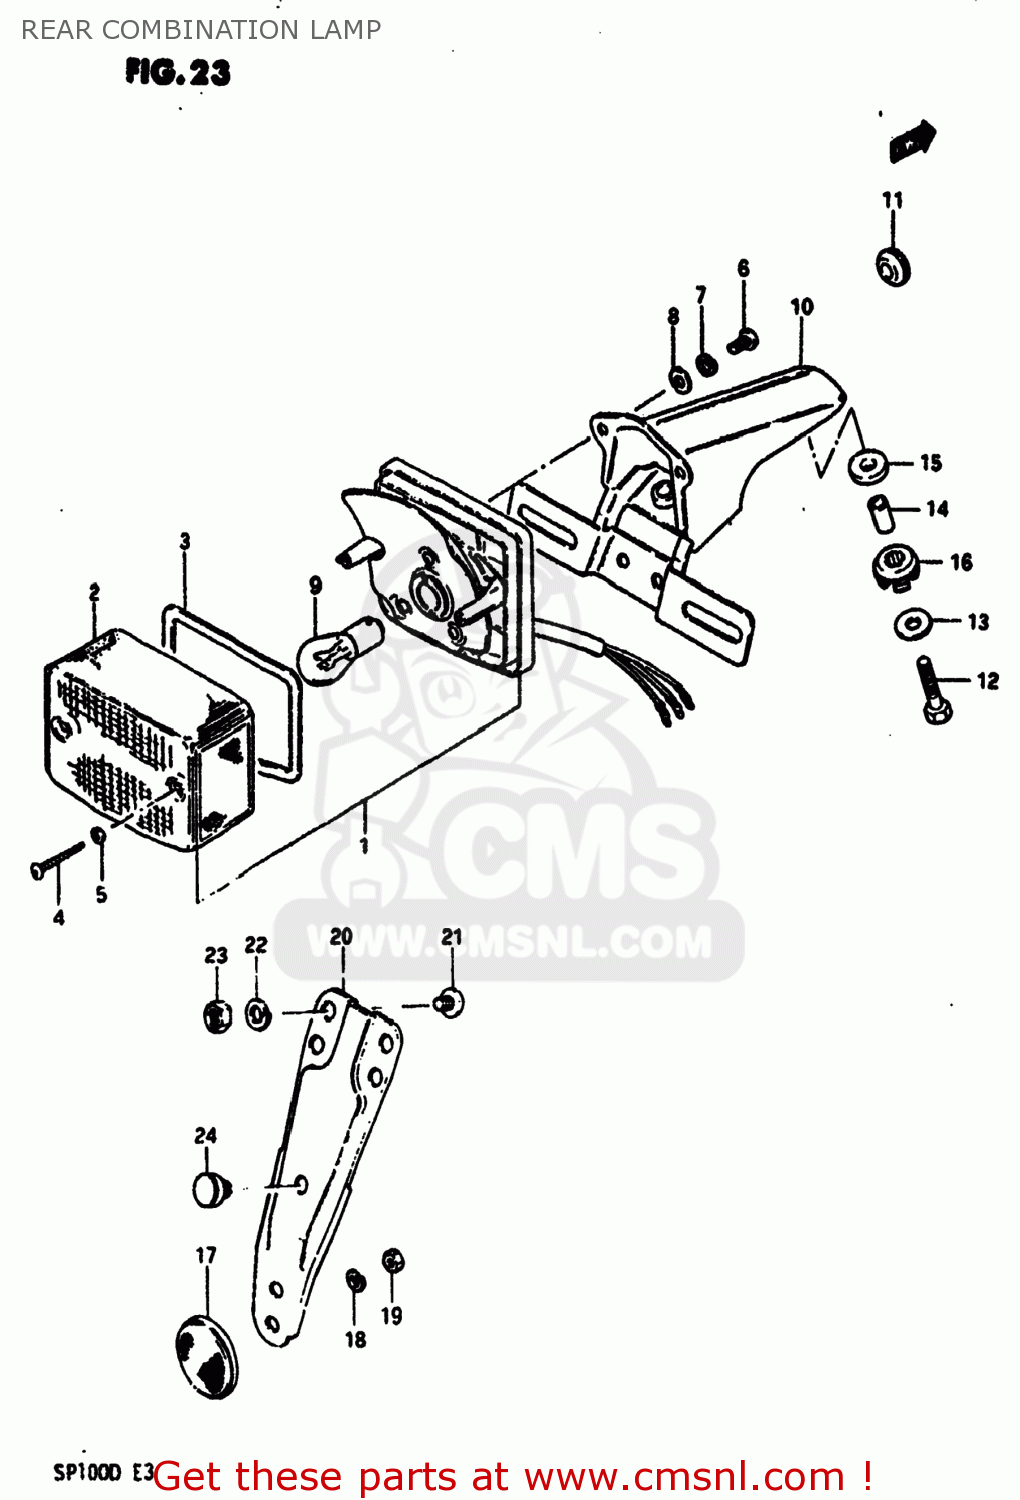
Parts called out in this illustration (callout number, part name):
1	LAMP UNIT,REAR COMBINATION
2	LENS
3	GASKET (NAS)
4	SCREW
5	GASKET (NAS)
6	SCREW
7	LOCK WASHER
8	WASHER
9	BULB(6V32/3CP,STANLEY)
10	BRACKET
11	GROMMET
12	BOLT
13	WASHER (6.5X20X1.2)
14	SPACER (6.1X8X15.5)
15	CUSHION
16	CUSHION
17	REFLEX REFLECTOR,RR
18	LOCK WASHER
19	NUT
20	BRACKET
21	SCREW
22	LOCK WASHER
23	NUT
24	CUSHION
